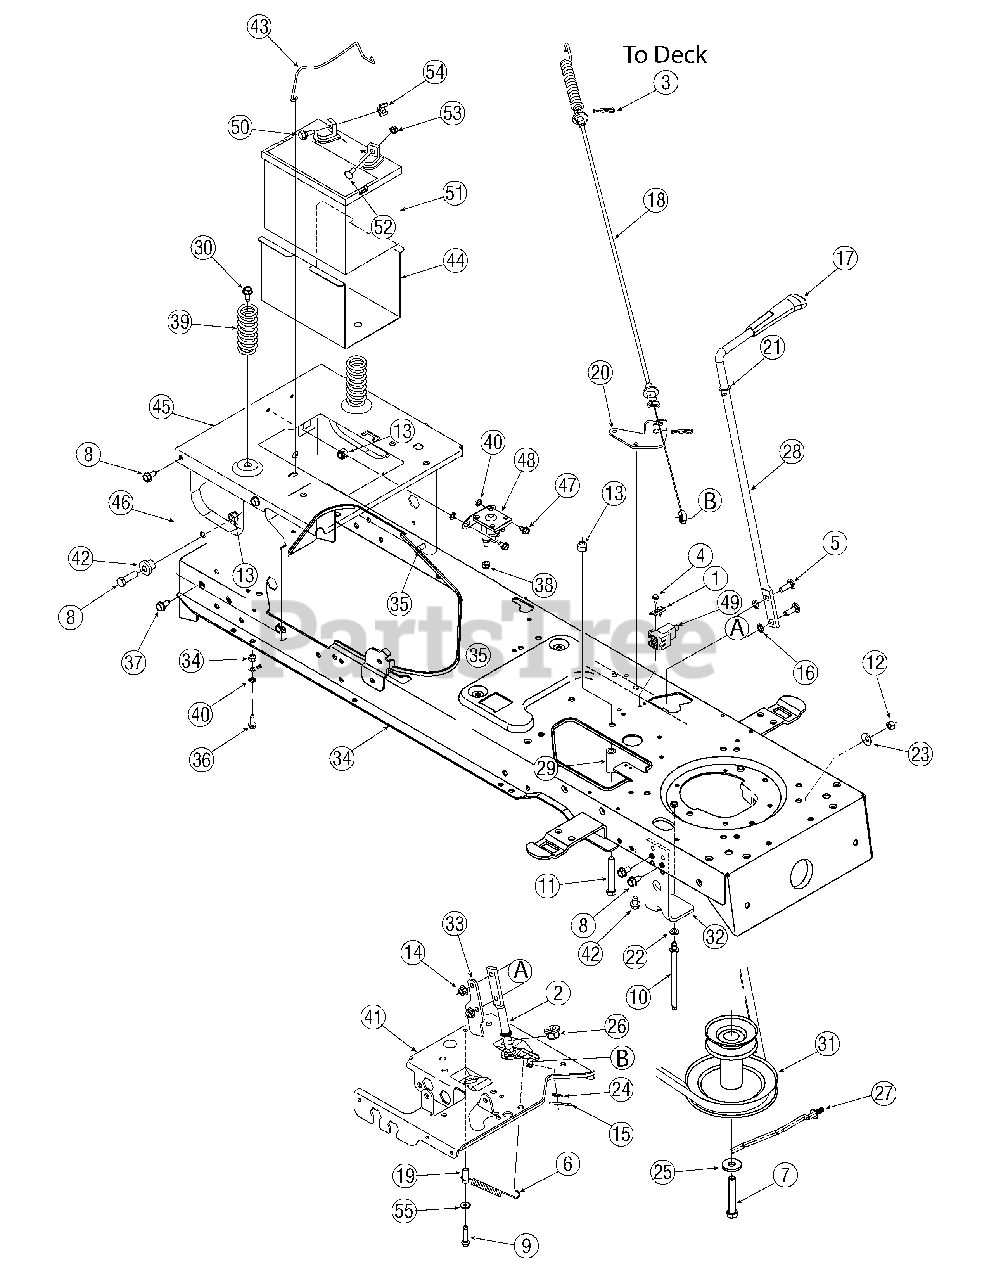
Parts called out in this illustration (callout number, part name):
1	Plate, Switch
2	Lever Assembly, Engagement
3	Click Pin
4	Screw, #10-16, 0.500
5	Screw, Carriage, 5/16-18, 1.00
6	Extension Spring, .38 OD x 3.9 LG
7	Screw, 7/16-20, 2.75, Gr5
8	Screw, 5/16-12, 0.750
9	Screw, 1/4-20 x 1.50
10	Pin, Belt Guard, 5/16 x 4.75
11	Screw, 3/8-16 x 2.25
12	Nut, Flange Lock, 5/16-18, GrF
13	Nut, Flange Lock, 3/8-16, GrF
14	Nut, Flange Lock, 5/16-18, Gr5
15	Pin, Cotter, 1/8 x 1.25
16	Nut, Speed, .3125 ID
17	Knob, PTO
18	Deck Engagement Cable
19	Spacer, .260 x .372 x 1.030 Lg.
22	Washer, Lock, 5/16
23	Washer, Bell, .340 x .872 x .060
24	Washer, Flat, .344 x .688 x .065
25	Washer, Flat, .450 x1.250 x.164
26	Bearing, Flange, Hex Split .500 ID
27	Keeper Rod, Belt
28	Engagement Handle, Deck
29	Spacer, .385 ID x .635
30	Screw, 5/16-18 x .750
31	Pulley, Engine, 3.39 x 6.12
36	Screw, 1/4-20, 0.750
37	Screw, 3/8-16, 1.25, Gr5
38	Nut, Flange Lock, 1/4-20,
39	Spring, Compr., 1.28 OD x 3.125
40	Washer, Lock, 1/4, External
42	Spacer, Shoulder, .38 x 1.0 x .70
43	Hold Rod, Battery
48	Solenoid, 12V, 100 Amp
49	Switch, Interlock
50	Screw, Shoulder, .250 x .150
51	Battery, 190 CCA
52	Screw, Carriage, 1/4-20, .75, Gr5
53	Nut, Sems, 1/4-20
54	Nut, Wing, 1/4-20
55	Washer, Flat, .28 x .74 x .063
